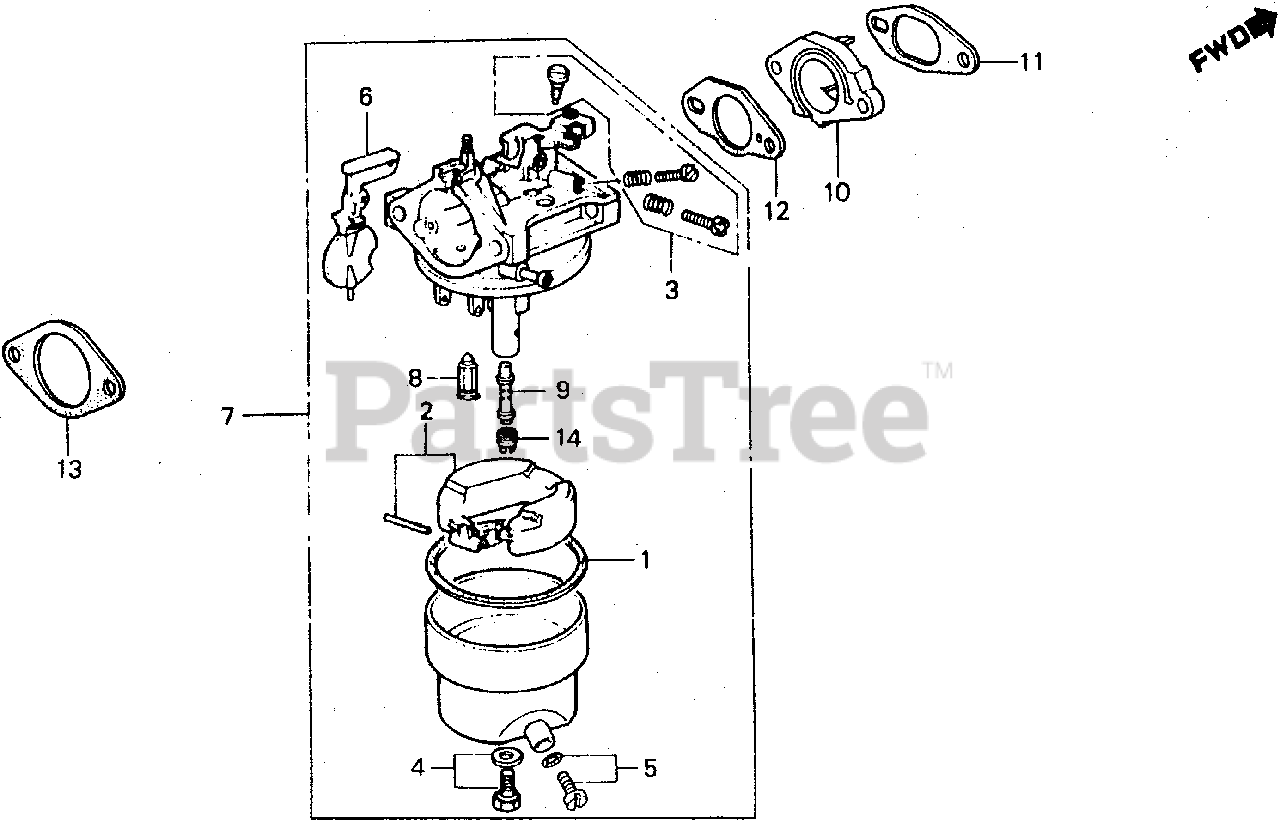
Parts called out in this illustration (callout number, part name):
1	GASKET SET
3	SCREW SET A
4	SCREW SET, DRAIN
5	SCREW SET B
7	CARBURETOR ASSY.
8	VALVE, FLOAT
9	NOZZLE, MAIN
10	INSULATOR, CARBURETOR
11	GASKET, INSULATOR
12	GASKET, CARBURETOR
13	GASKET, AIR CLEANER
14	JET, MAIN (#72)
